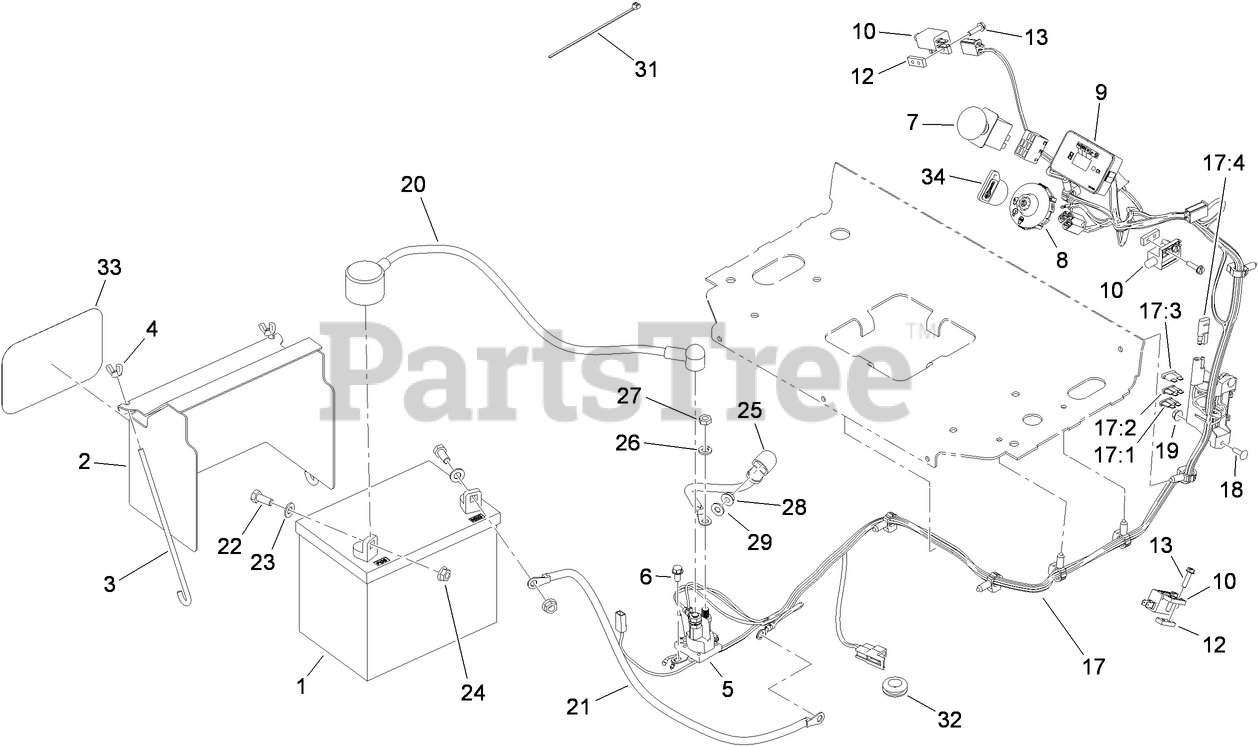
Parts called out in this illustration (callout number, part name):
1	BATTERY
2	COVER-BATTERY
3	BOLT-HOLDDOWN
4	WINGNUT
5	SOLENOID
6	SCREW-HWH
7	SWITCH-PTO, ON-ON-(ON)
8	SWITCH-IGNITION
9	MODULE-METER, HOUR
10	SWITCH-CLOSED, NORMALLY
12	PLATE-TAPPED
13	SCREW-HWH
17	HARNESS-WIRE
17:1	FUSE-BLADE, 30 AMP
17:2	FUSE-BLADE, 25 AMP
17:3	FUSE-BLADE, 10 AMP
17:4	CAP-PLUG
18	BOLT-CARR
19	NUT-HF
20	CABLE-BATTERY, POSITIVE
21	CABLE-BATTERY, BLACK
22	SCREW-HH
23	WASHER-PLAIN
24	NUT-HHF, SMOOTH
25	CABLE-BATTERY, RED
26	WASHER-LOCK
27	NUT-JAM
28	NUT-HF
29	WASHER-FLAT
31	TIE-CABLE
32	GROMMET
33	DECAL
34	KEY-IGNITION
